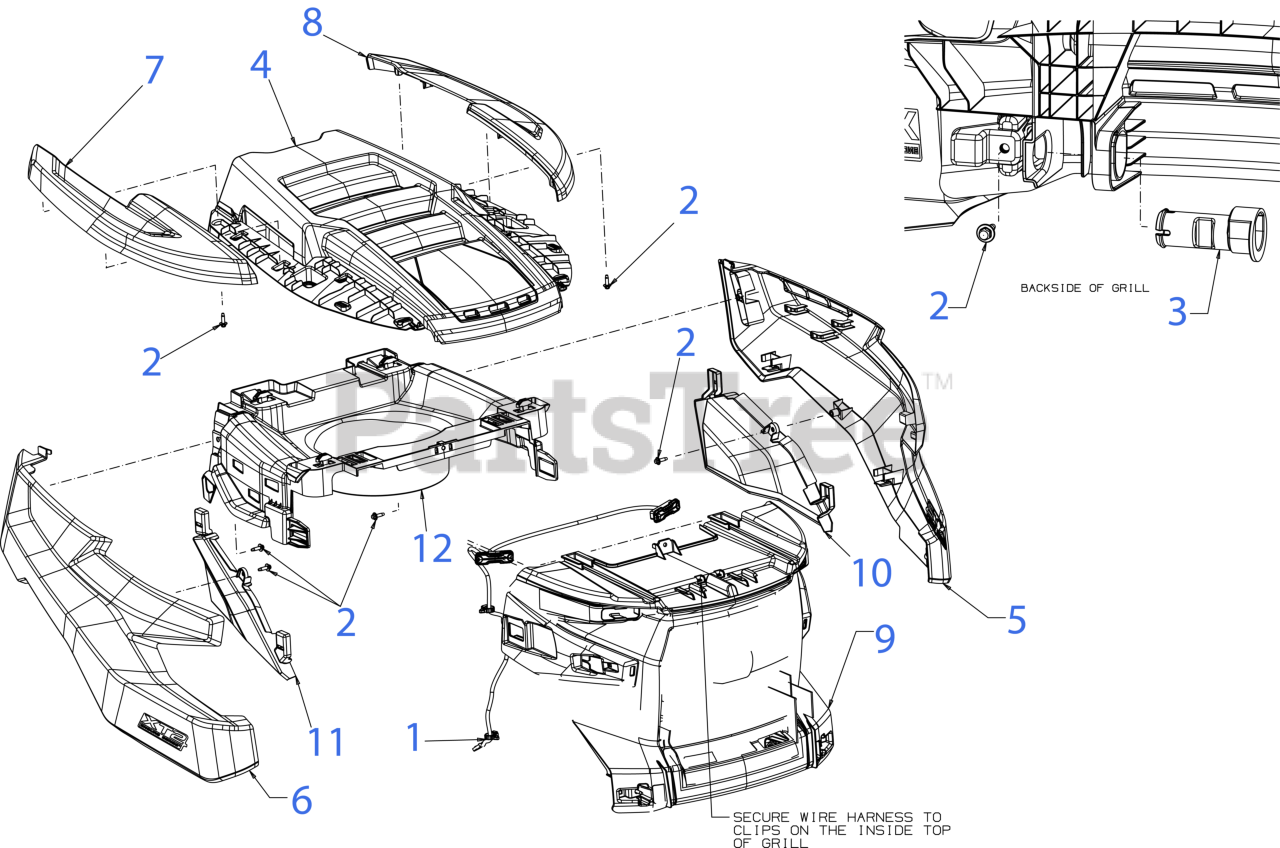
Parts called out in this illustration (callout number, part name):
1	HEADLIGHT HARNESS (W/LED)
2	SCREW 1/4-10 x .750
3	HOOD PIVOT PIN
4	HOOD (TOP)
5	PANEL (UPPER SIDE) (LH)
6	PANEL (UPPER SIDE) (RH)
7	HOOD (TOP) (RH)
8	HOOD (TOP) (LH)
9	GRILLE (FRONT) (T STYLE)
10	PANEL (LOWER SIDE) (LH)
11	PANEL (LOWER SIDE) (RH)
12	FRAME (PLENUM/HOOD)
